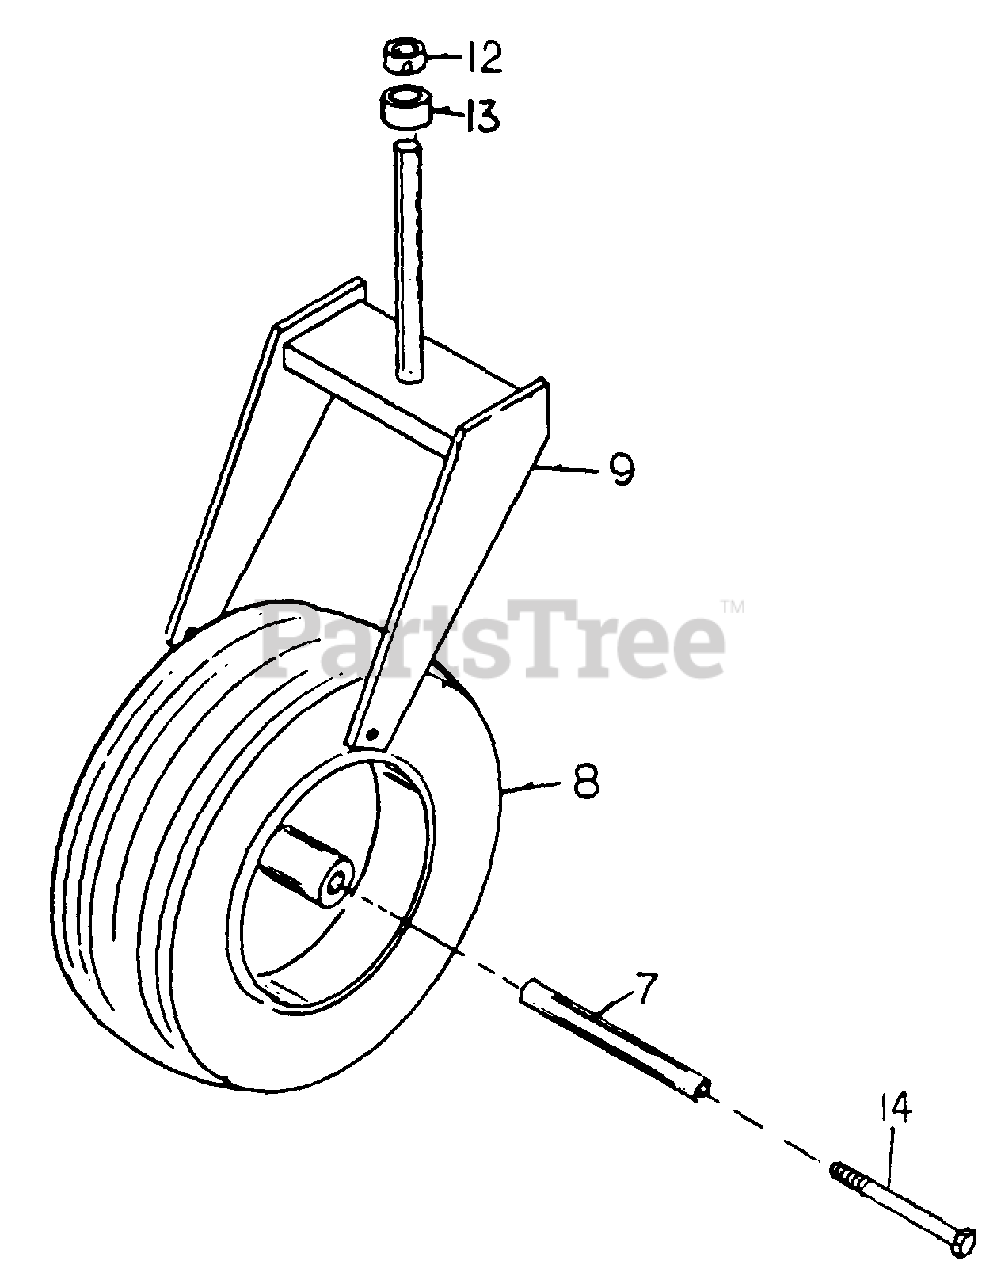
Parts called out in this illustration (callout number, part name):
7	Axle
8	Tail Wheel Assembly
9	Tail Wheel Fork
12	Set Collar, 1"
13	Spacer, Tail Wheel Fork
14	Hex Capscrew, 1/2-13 x 8 1/2"
